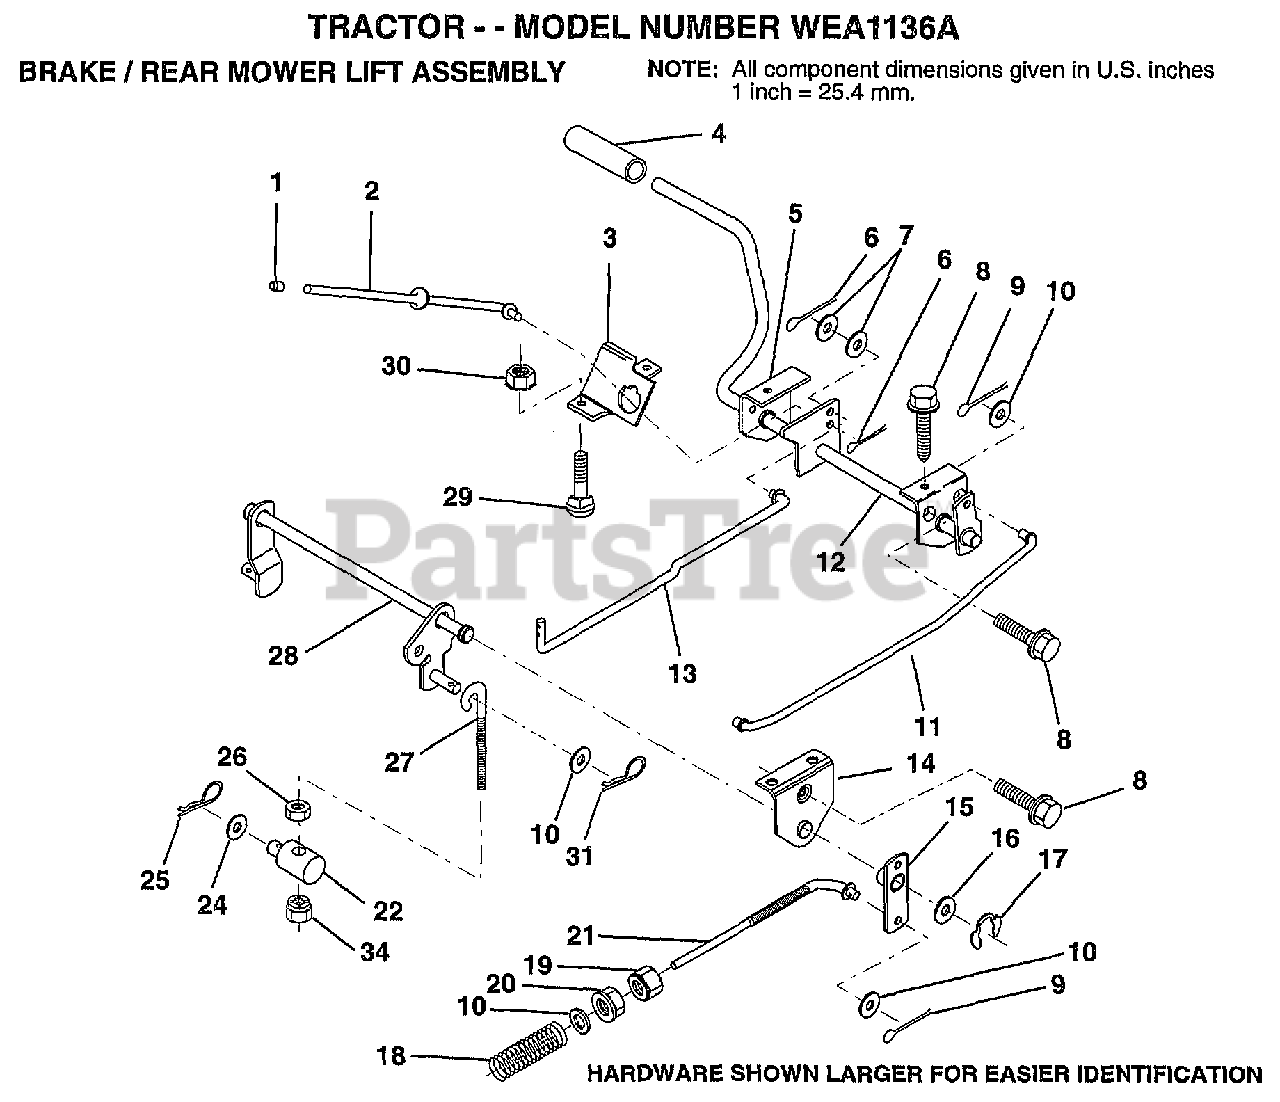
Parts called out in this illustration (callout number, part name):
1	PLUNGER CAP T
2	"ROD,PARK BRAKE"
3	"BRKT,PARK BRAKE"
4	FOOT PEDAL COVER
5	"BRKT,CLU PEDAL LH"
7	WASHER
9	COTTER PIN
10	WASHER
11	"ROD,FRT BRAKE"
12	PEDAL ASM CL/BK36
13	"ROD,CLUTCH"
14	"BRKT,LIFT SHAFT"
15	PVT BRAKE ARM ASM
16	WASHER T
17	KLIP RING
18	SPRING ROD BRAKE
19	NUT
20	NUT
22	TRUNNION.LIFT.
24	WASHER
26	LOCKNUT
27	"LINK, MOWER REAR"
28	LIFT ASM MOW REAR
31	RETAINER.SPRING
